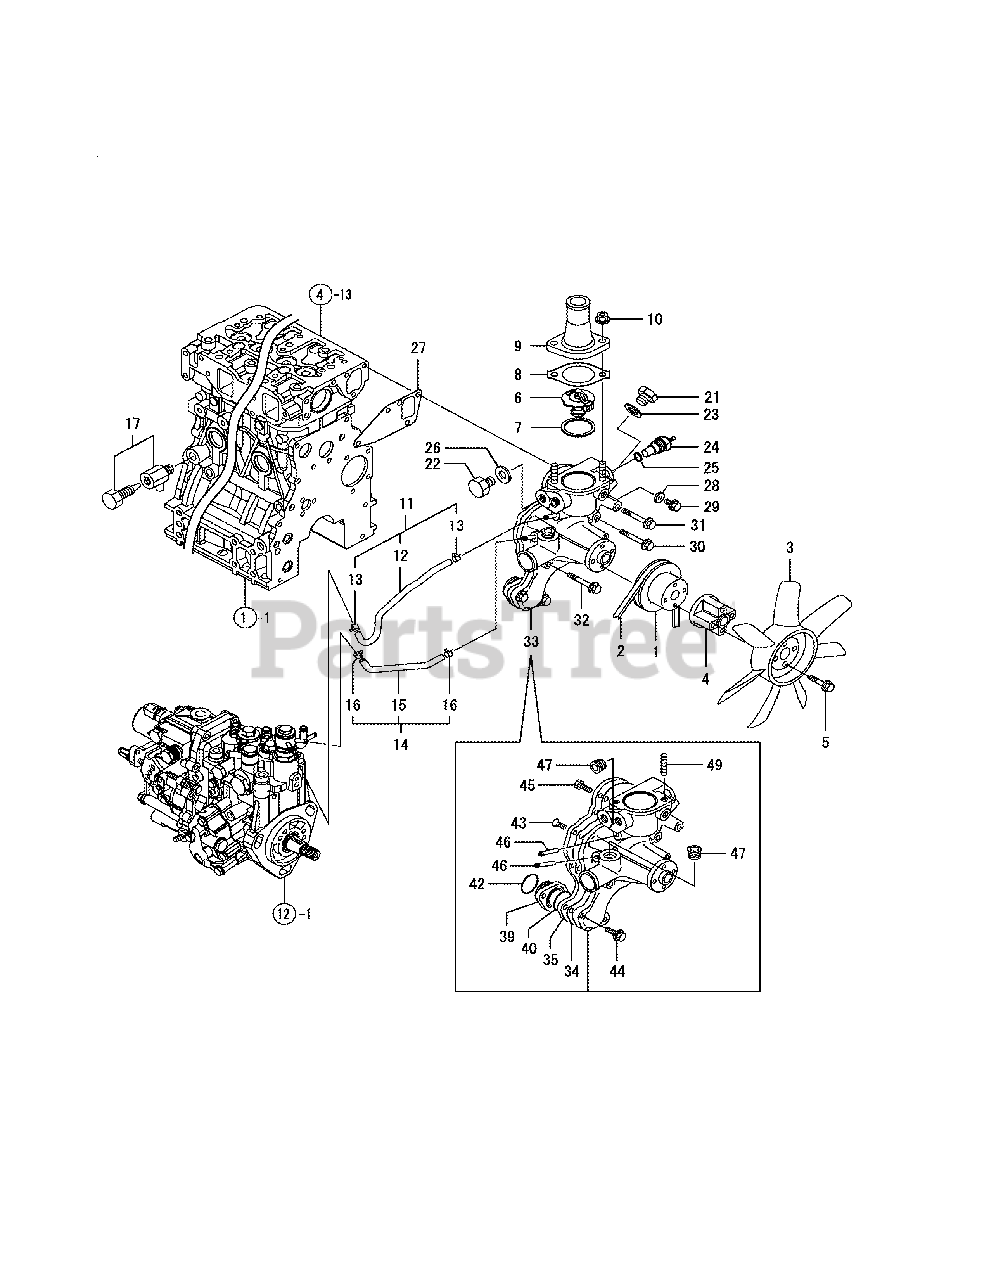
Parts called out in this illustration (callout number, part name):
1	V-PULLEY(D=120)
3	FAN, COOLING (D=360)
5	BOLT M 6X 50 PLATED
6	THERMOSTAT (71)
7	GASKET, (NON-ASB.)
8	GASKET, (NON-ASB.)
9	COVER, THERMOSTAT
11	PIPE, COOLING WATER
12	PIPE, COOLING WATER
14	PIPE, COOLING WATER
15	PIPE, COOLING WATER
17	DRAIN ASSY 1/4
26	SEAL WASHER 12
28	GASKET 8, ROUND
29	BOLT M 8X 12 PLATED
30	BOLT M 8X 55 PLATED
31	BOLT M 8X 60 PLATED
32	BOLT M 8X 70 PLATED
33	PUMP ASSY, WATER
39	FLANGE, PUMP
40	O-RING 5 24031
44	BOLT M 6X 20 PLATED
47	PLUG PT3/8,STEEL
